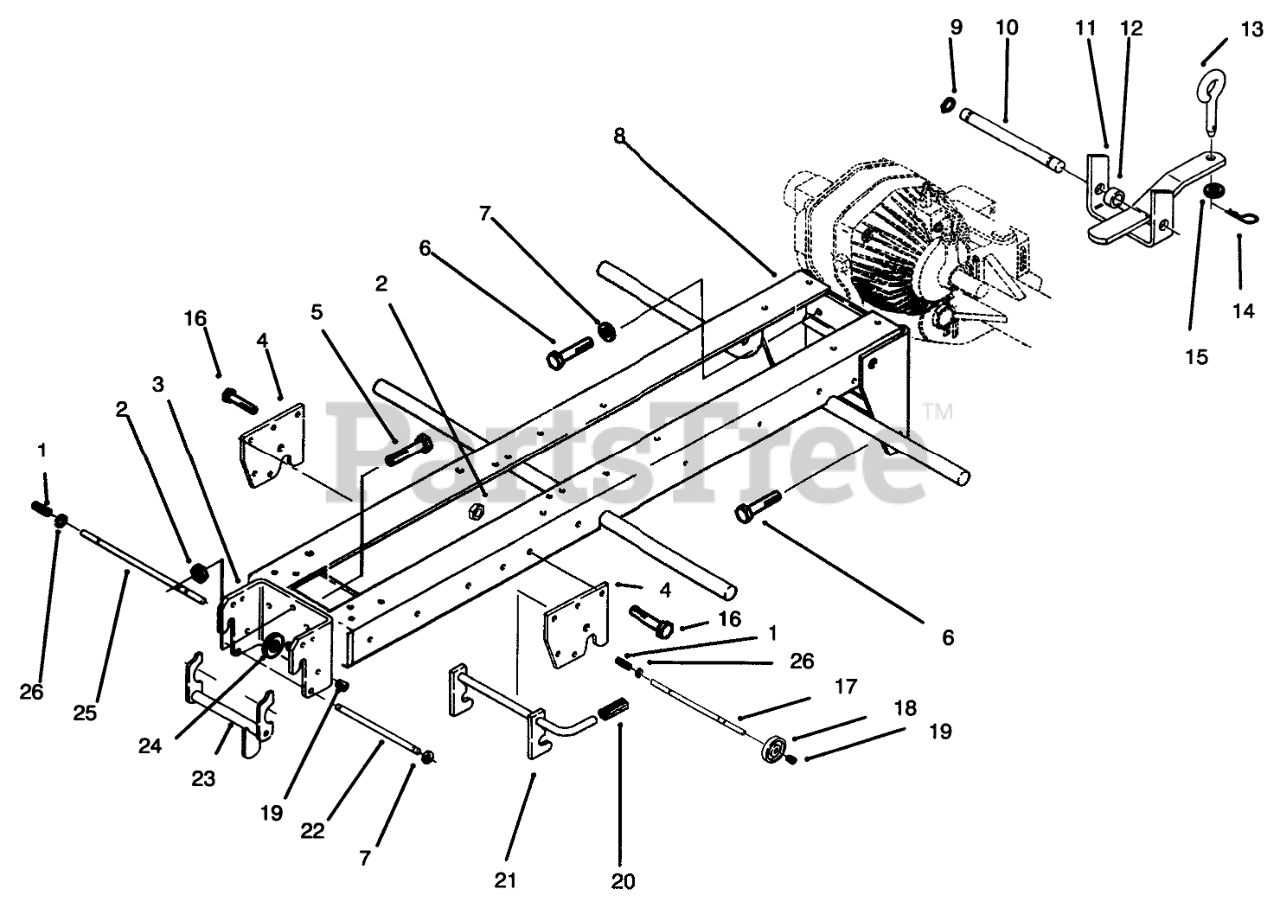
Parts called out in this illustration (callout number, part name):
1	SPRING
2	NUT-LOCK, NI
3	Front Hitch
4	Hitch Plate
5	BOLT-CARR
6	SCREW-HH
7	WASHER-LOCK
8	WELD FRAME R
9	E-RING
10	PIN-STATIONARY HITCH
11	Hitch
12	SPACER
13	PIN-TOOL
14	PIN-HAIR
15	WASHER-FLAT
16	SCREW-HH
18	ROD-LOCK
19	CAP-ROD, PLUNGER
20	GRIP
21	MID HITCH ASM
22	ROD-LATCH PIVOT
23	LATCH
25	ROD-LOCK
26	RING-RETAINING
